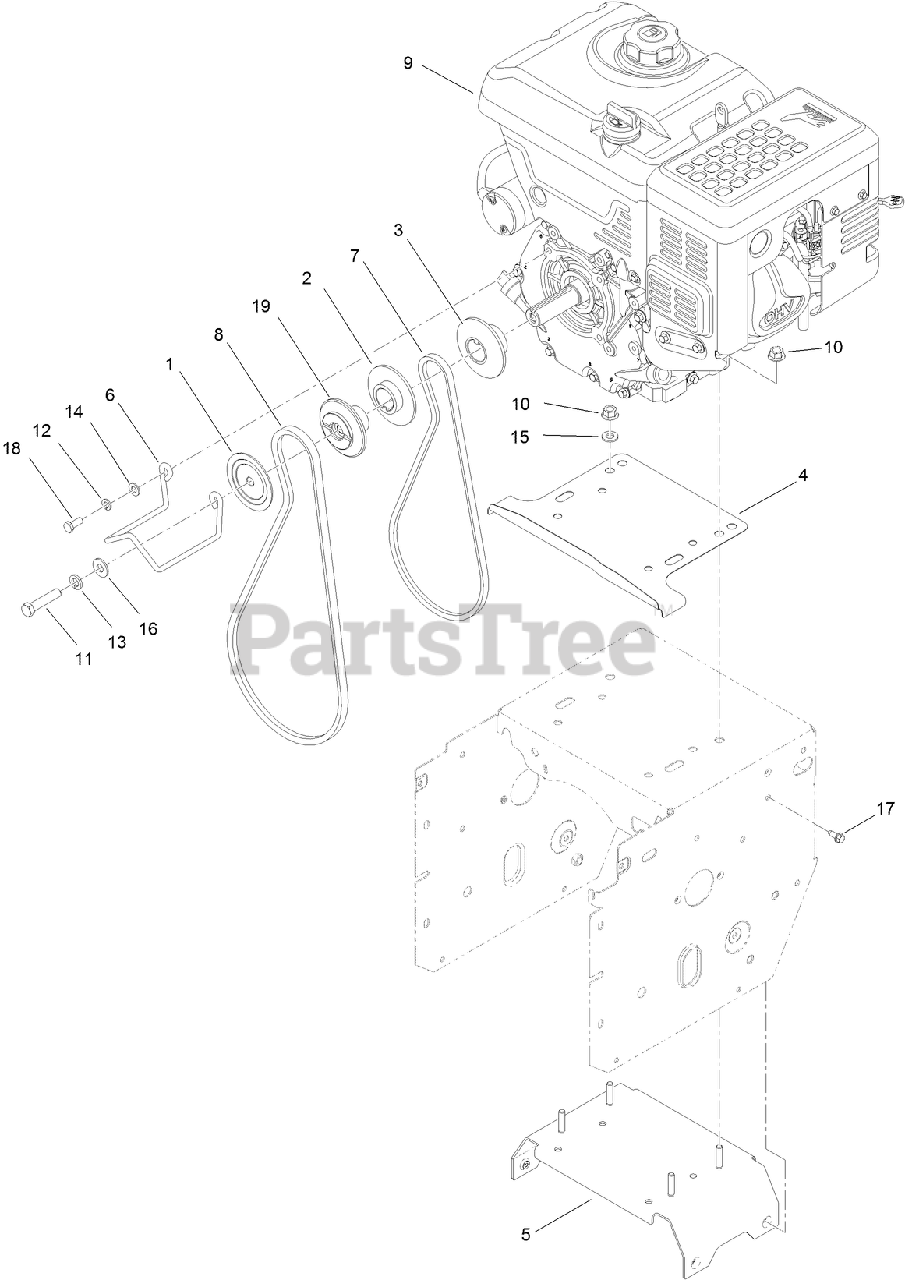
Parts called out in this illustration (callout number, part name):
1	SHEAVE-HALF, IMPELLER
2	PULLEY-ENGINE, TRACTION
3	SHEAVE-HALF, TRACTION
4	SHIELD-DRIVE
5	FRAME BRACE ASM
7	BELT-V
8	BELT-V
9	ENGINE-175FDS-1
10	NUT-FLANGE
11	SCREW-HH
12	WASHER-LOCK
13	WASHER-LOCK
14	WASHER-PLAIN
15	WASHER-FLAT
16	WASHER-FLAT
17	SCREW-HWH
18	SCREW-HH
19	PULLEY-ENGINE, IMPELLER
